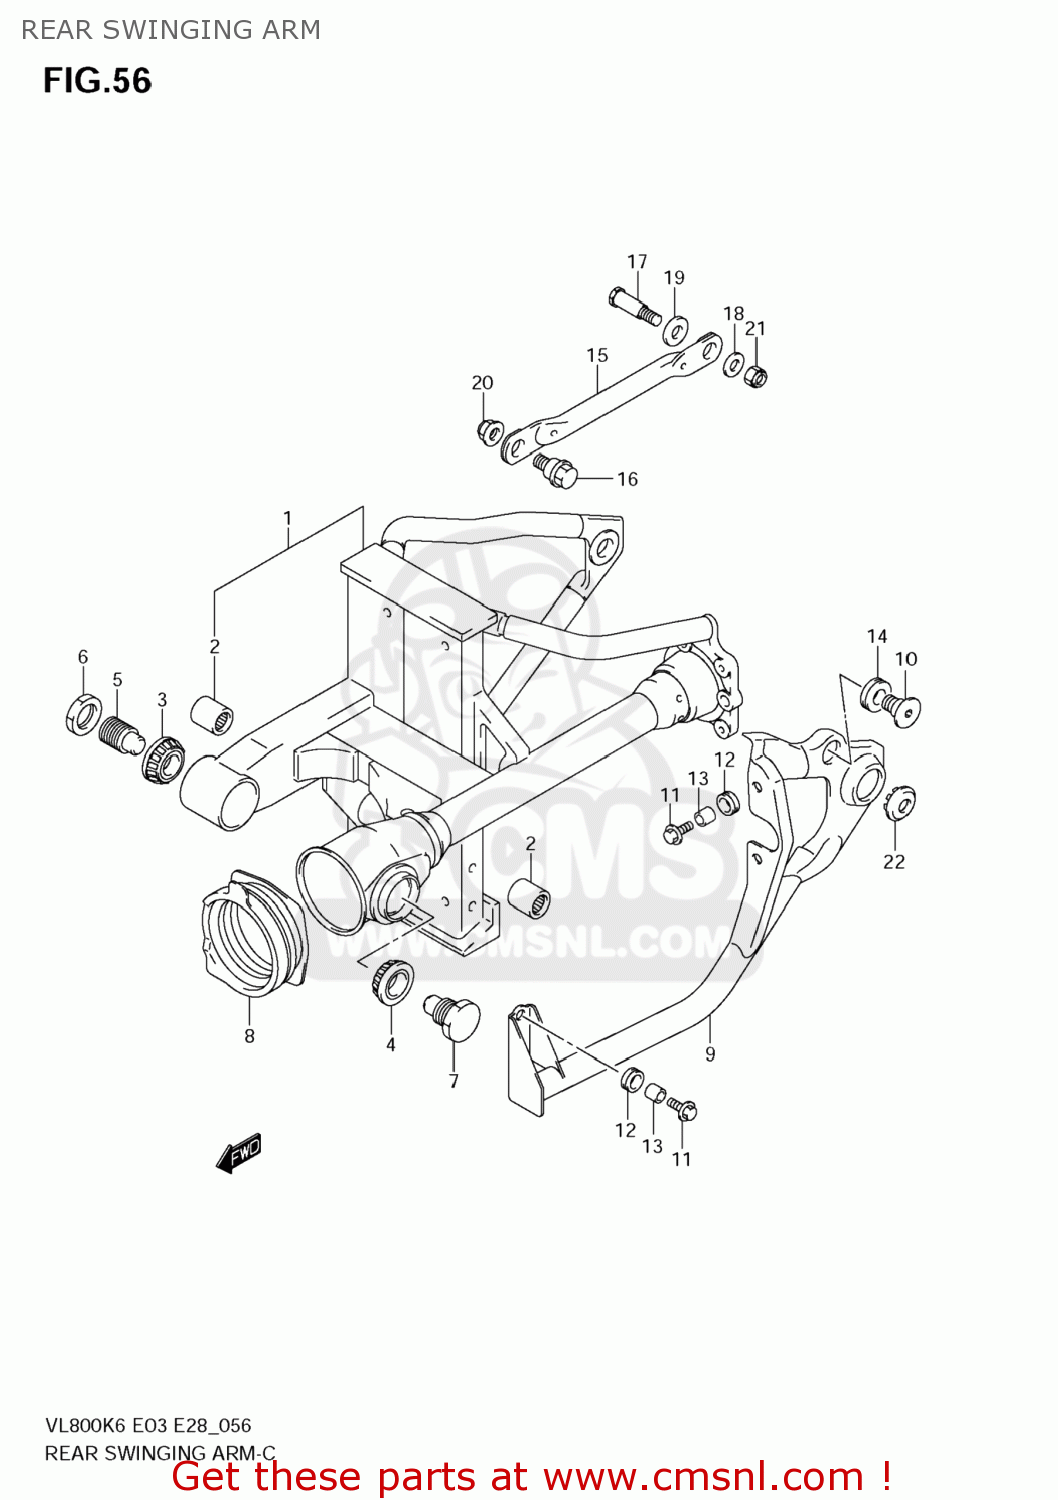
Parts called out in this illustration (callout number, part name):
1	SWINGINGARM SET,RR
2	BEARING(17X24X25)
3	BEARING(17X40X13.25)
4	BEARING(17X40X13.25)
5	BOLT,RR SWGARM PIVOT
6	NUT
7	BOLT,SWINGINGARM PIVOT,L
8	BOOT,PROPELLER SHAFT
9	COVER,RR SWINGINGARM,L(BLACK)
10	BOLT,RR SWGARM
11	BOLT(6X20)
12	CUSHION
13	SPACER(6.5X10X9.4)
14	CUSHION
15	TORQUE LINK,RR
16	BOLT(10X22)
17	BOLT(10X41)
18	WASHER(10X20X2.3)
19	CUSHION
20	NUT
21	NUT
22	CAP,FRAME PIVOT
